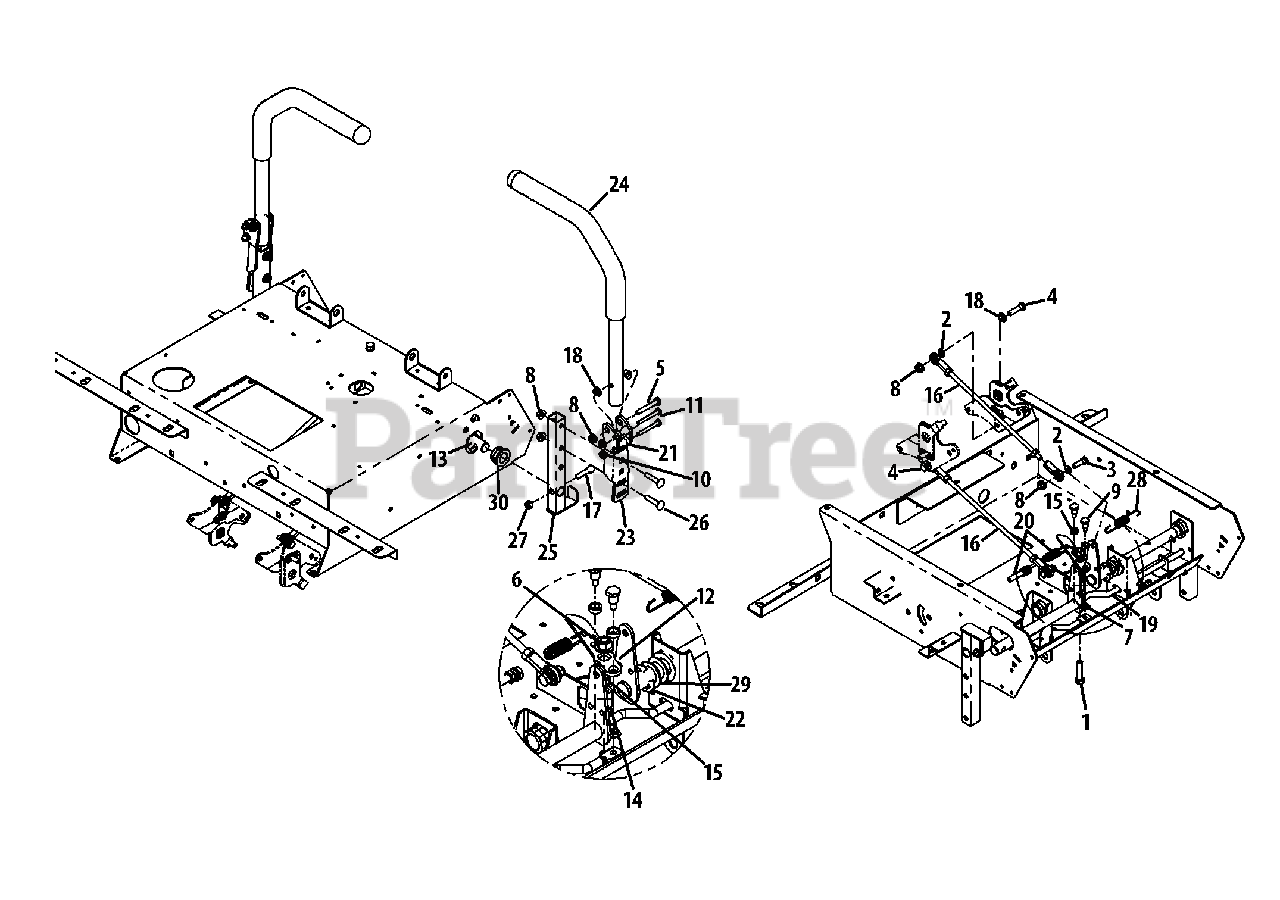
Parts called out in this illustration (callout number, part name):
1	Hex Cap Screw, 3/8-16 x 1-1/2
2	Flat Washer, .3175 x .500 x .045
3	Hex Head Cap Screw, 5/16-18 x 1.00
4	Hex Screw, 5/16-18 x 1-1/4
5	Hex Cap Screw, 5/16-18 x 2.00
6	Counterlock Flange Nut, 3/8-16
7	Flat Washer, .250 x .630 x .052
8	Nut, 5/16-18, Centerlock
9	Shoulder Screw, 1/4-28
10	Hex Flange Lock Nut, 1/4-20
11	Hex Cap Screw, 1/4-20 x 2.00
12	Brake Lever Plate
13	Steering Input Shaft Assembly
14	Spacer, .385 x .625 x .869
15	Spacer, .380 x .563 x .196
16	Steering Link Rod
17	Socket Head Capscrew, 5/16-18 x 1.25
18	Bushing, .310 x .172 x .688 x .06
19	Control Lock Rod
20	Control Cable Lock Out
21	Spacer, .25 x .38 x 1.13
22	E-Clip Retainer Ring
23	Lapbar Pivot Bracket
24	Lapbar Handle/Grip Assembly
25	Pivot Bracket Weldment
26	Carriage Bolt, 5/16-18 x 1.50
27	Nylock Nut, 5/16-18
28	Extension Spring, .544 x 3.35
29	Flat Washer, .793 x 1.24 x .060
30	Hex Flange Bearing, .752
